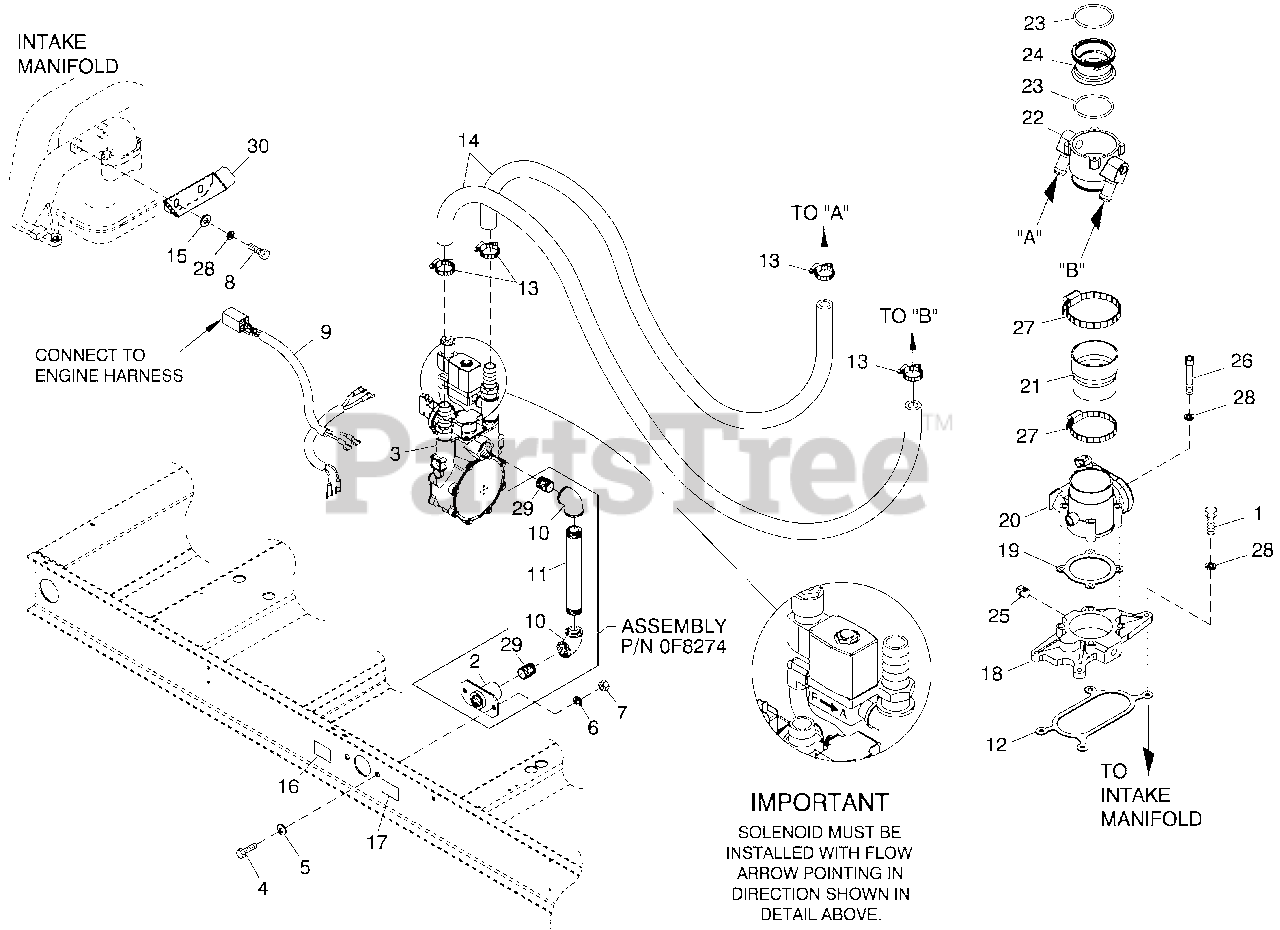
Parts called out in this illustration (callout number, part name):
1	SCREW HHC M6-1.0 X 35 G8.8 BLK
2	FLANGE FUEL INLET
3	REG ASSY 6.8L 70KW LPV CPL
4	SCREW HHC M8-1.25X 20 G8.8
5	WASHER FLAT 5/16-M8 ZINC
6	WASHER LOCK M8-5/16
7	NUT HEX M8-1.25 G8 CLEAR ZINC
8	SCREW HHC M6-1.0X 20 G8.8
9	HARNESS,FUEL JUMPER SINGLE REG
10	ELBOW 90D 3/4NPT
11	NIPPLE PIPE 3/4NPT X 7
12	GASKET ADAPTER THROT BODY
13	CLAMP HOSE #10 .56-1.06
14	HOSE 3/4 ID SAE-30R2 (38.5" LG)
15	WASHER FLAT M6
16	DECAL INLET PRESSURE
17	DECAL FUEL INLET NG (NATURAL GAS APPLICATION)
18	ASSY,ADAPTER,THROTTLE BODY
19	GASKET, GOVERNOR ACTUATOR
20	ACTUATOR BOSCH 60, GOVERNOR
21	REDUCER 3.0" TO 2.75" TURBO
22	MIXER, 40/60MM ACTUATOR ASSY
23	O-RING 2-3/4X3/32X2-15/16
24	VENTURI, THROTTLE 36MM
25	PLUG STD PIPE 1/4 STEEL SQ HD
26	SCREW SHC M6-1.0 X 50 C8.8
27	CLAMP HOSE #44 2.31-3.25
28	WASHER LOCK M6-1/4
29	NIPPLE CLOSE 3/4X1.375
30	BRACKET, HOSE RISER
